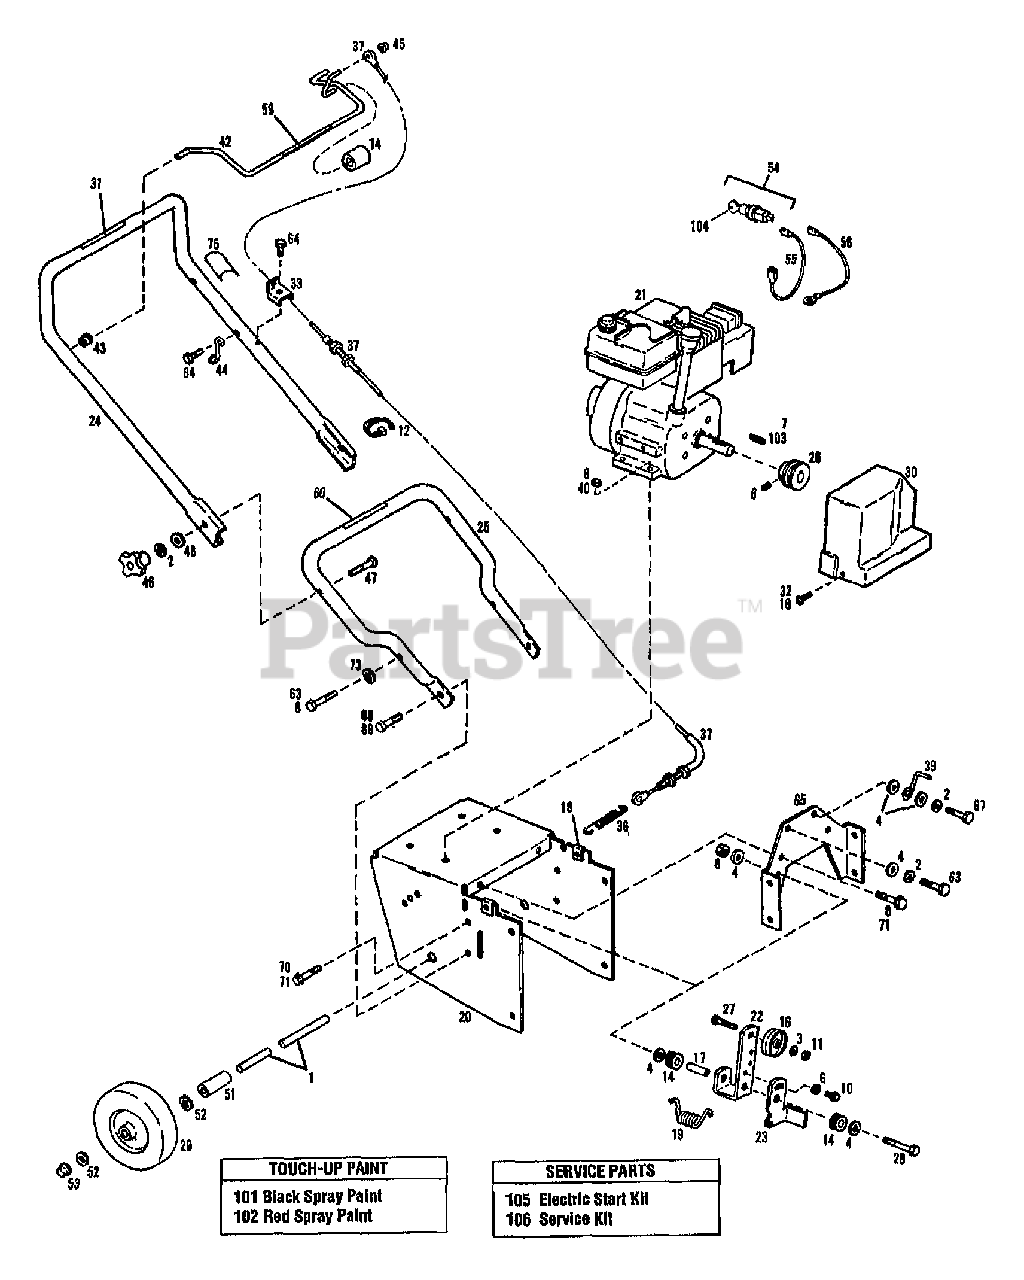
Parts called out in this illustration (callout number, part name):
1	AXLE-WHEEL
2	WASHER-LK .312 ZP
3	WASHER-LK .375 @ DEPL
4	WASHER-FLAT 5/16 SAE
6	WASHER-FLAT 1/4 SAE
7	KEY-.187 SQ X .75
8	NUT-TOP/LK 5/16-18 ZP
9	SCR-SET 5/16-18 X 5/16
10	SCR 1/4-20X.5 FL SELF TAP
11	NUT-HEX 3/8-16 ZP
12	TIE-CABLE NYLON BLACK
14	BUSHING-.5X.5 NYLON FLNG
16	IDLER-FLAT
17	SPACER-.5X.334X1.79
18	NUT-SPEED #10
19	SPRING-TORSION
21	ENGINE, 4HP TECUMSEH, MODEL HSSK40-55610S
22	ARM-IDLER
23	ARM-BRAKE
24	HANDLEBAR-UPPER
25	HANDLEBAR-LOWER
26	SHEAVE-ENGINE
27	SCR-CARR 3/8-16X1.50 G5 ZP
28	SCR-HH 5/16-18X2.75 G5 ZP
29	ASSM-TIRE & WHEEL
30	COVER-BELT SC
31	DECAL-SC
32	SCR-TRUSS #10-24 X 5/8
33	BRKT-CONTROL CABLE
36	SPRING-EXT
37	CABLE-AUGER DR
39	GUIDE-BELT
40	SCR-HH 5/16-18X1.5 G5 ZP
42	LEVER-CONTROL
43	BEARING-FLANGED
44	SUPT-CHUTE CRANK
45	CAP-PUSH ON .312 DIA
47	SCR-CURVED HD 5/16-18X2.0
48	WASHER-FLAT 5/16 SAE
51	SPACER-.656X.512X1.0
52	WASHER-FLAT .88X.5X.06 ZP
53	CAP-PUSH ON
54	SWITCH-IGN W/HDW & KEYS
55	LEAD-SC
56	LEAD SC
59	DECAL-SC
63	SCR-HH 5/16-18X1.25 G5ZP
64	SCR-FLANGE 1/4-20X3/4 GR5
65	SUPPORT-ENGINE
67	SCR-HH 5/16-24X1.00 G5ZP
69	NUT-HFLK 3/8-16 ZP
71	NUT-HFLK 5/16-18 ZP
73	WASHER-FLAT 5/16 SAE
74	GRIP-HANDLE
75	DECAL-CHUTE CONTROL
101	PAINT-BLACK SPRAY
102	PAINT-RED SPRAYCAN POWDER
103	LOCTITE-242 (.5 ML TUBE)
104	KEY-IGNITION
105	ELEC START-5HP SNW
106	KIT-SVC 4HP SNOWTHROWER
